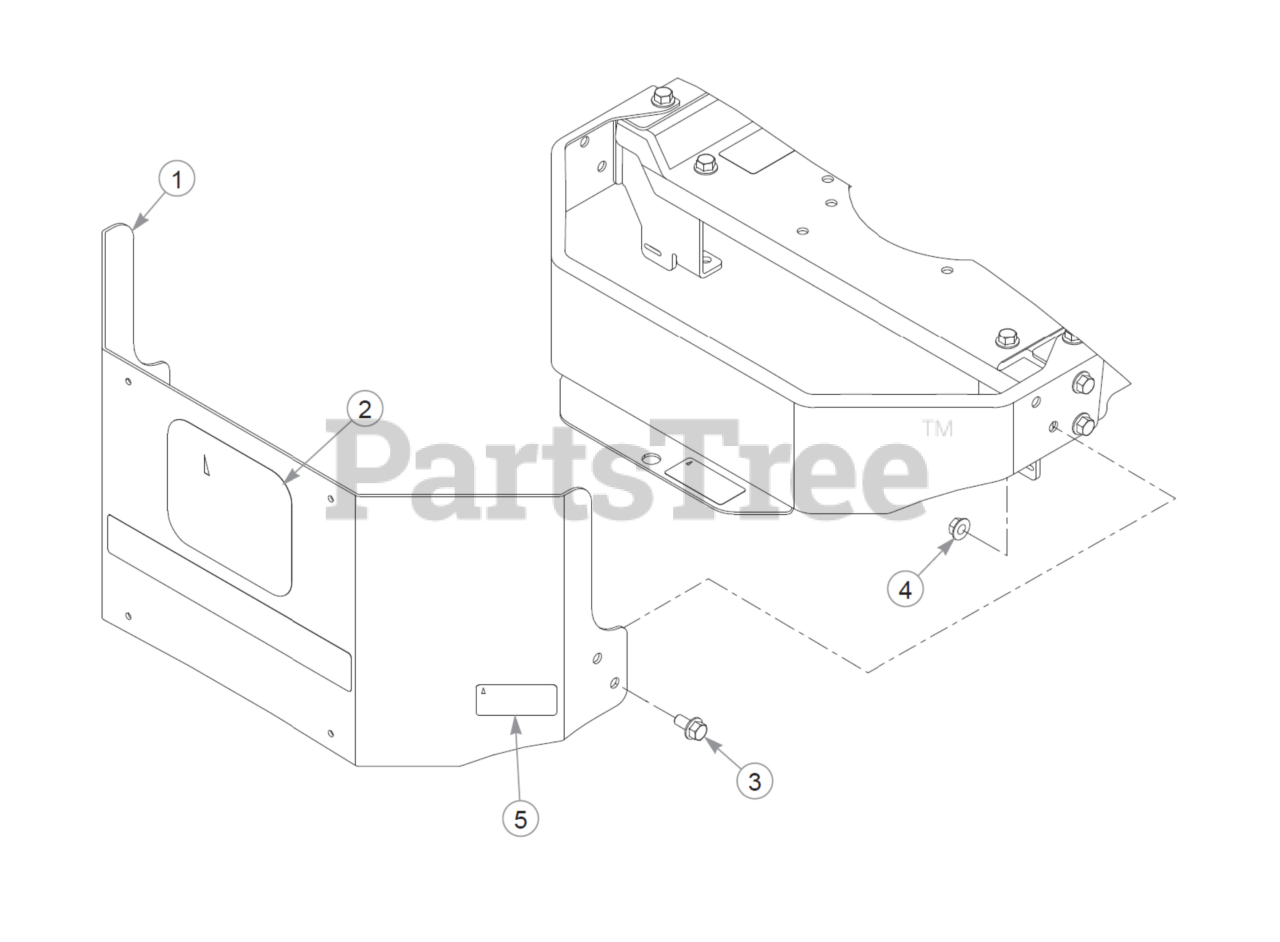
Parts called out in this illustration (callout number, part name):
1	KIT, ENGINE GUARD
2	DECAL, H LOGO, MFSD 36/4
3	CS .375-16X0.75 HXF G5ZN
4	NT .375-16 FLKG5
5	DECAL, HOT
